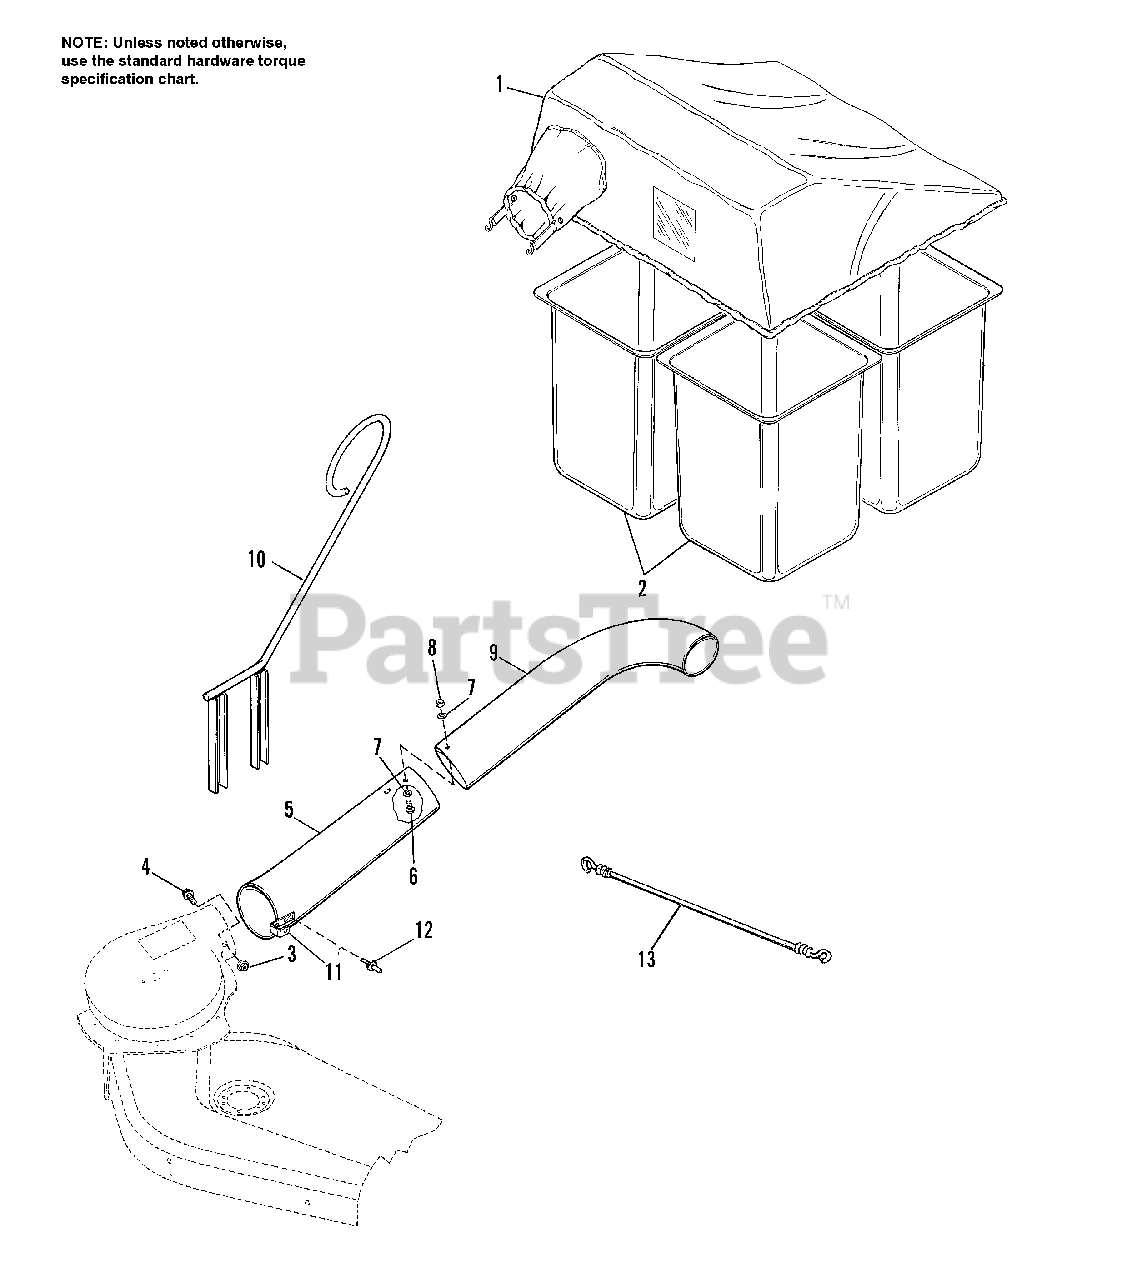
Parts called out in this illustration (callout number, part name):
2	BASKET, Grass Collector
3	NUT, Hex, Flange, Lock, 1/4-20
4	CARRIAGE BOLT, 1/4-20 x 5/8
5	TUBE ASSY., Lower
6	SCREW, Truss Hd., #10-32 x 1/2
7	WASHER, Plain, #10
8	NUT, Hex, Washer Assy., #10-32
9	TUBE, Upper
10	SUPPORT, Tube
11	CLIP, Spring
